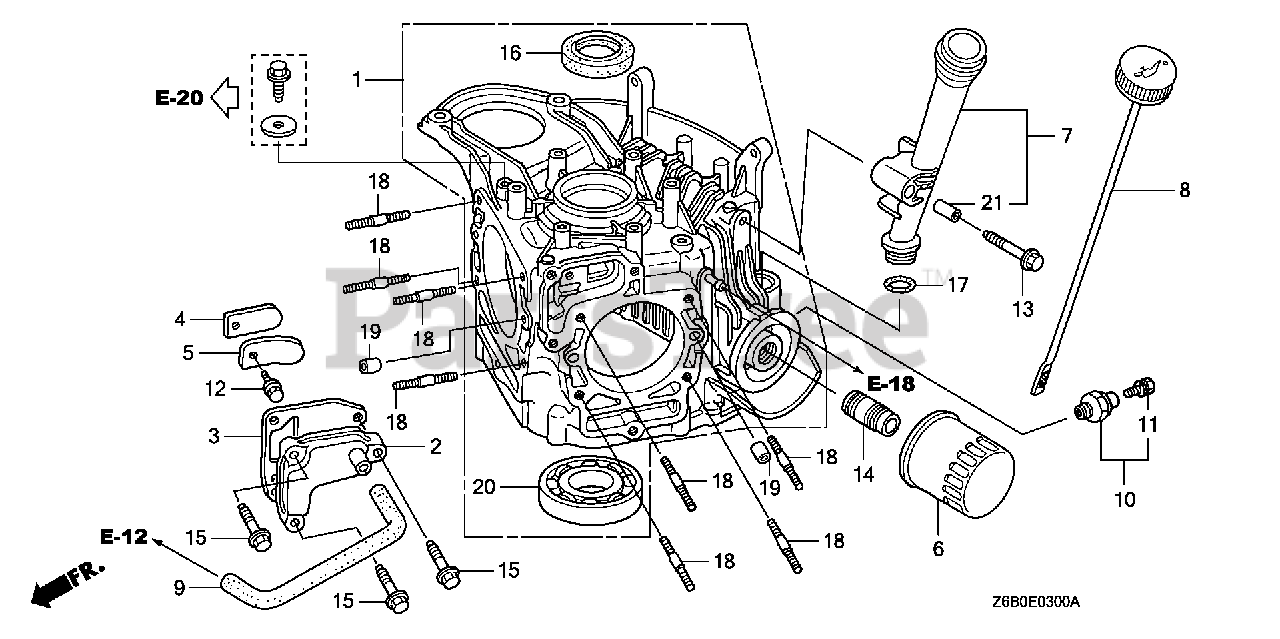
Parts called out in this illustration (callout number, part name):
1	CRANKCASE ASSY.
2	COVER, BREATHER
3	GASKET, BREATHER COVER
4	PLATE, VALVE
5	STOPPER, VALVE
6	FILTER, OIL (TOYO ROKI)
7	EXTENSION, OIL FILLER
8	DIPSTICK, OIL
9	TUBE, BREATHER
10	SWITCH ASSY., OIL PRESSURE
11	BOLT-WASHER (4X8) (DENSO)
12	BOLT, FLANGE (5X10)
13	BOLT, FLANGE (6X45) (CT200)
14	HOLDER, OIL FILTER
15	BOLT, FLANGE (6X25) (CT200)
16	OIL SEAL (35X52X8)
17	O-RING (22.1X2.2)
18	BOLT, STUD (8X28)
19	PIN, DOWEL (8X14)
20	BEARING, RADIAL BALL (6207)
21	COLLAR, EXTENSION
